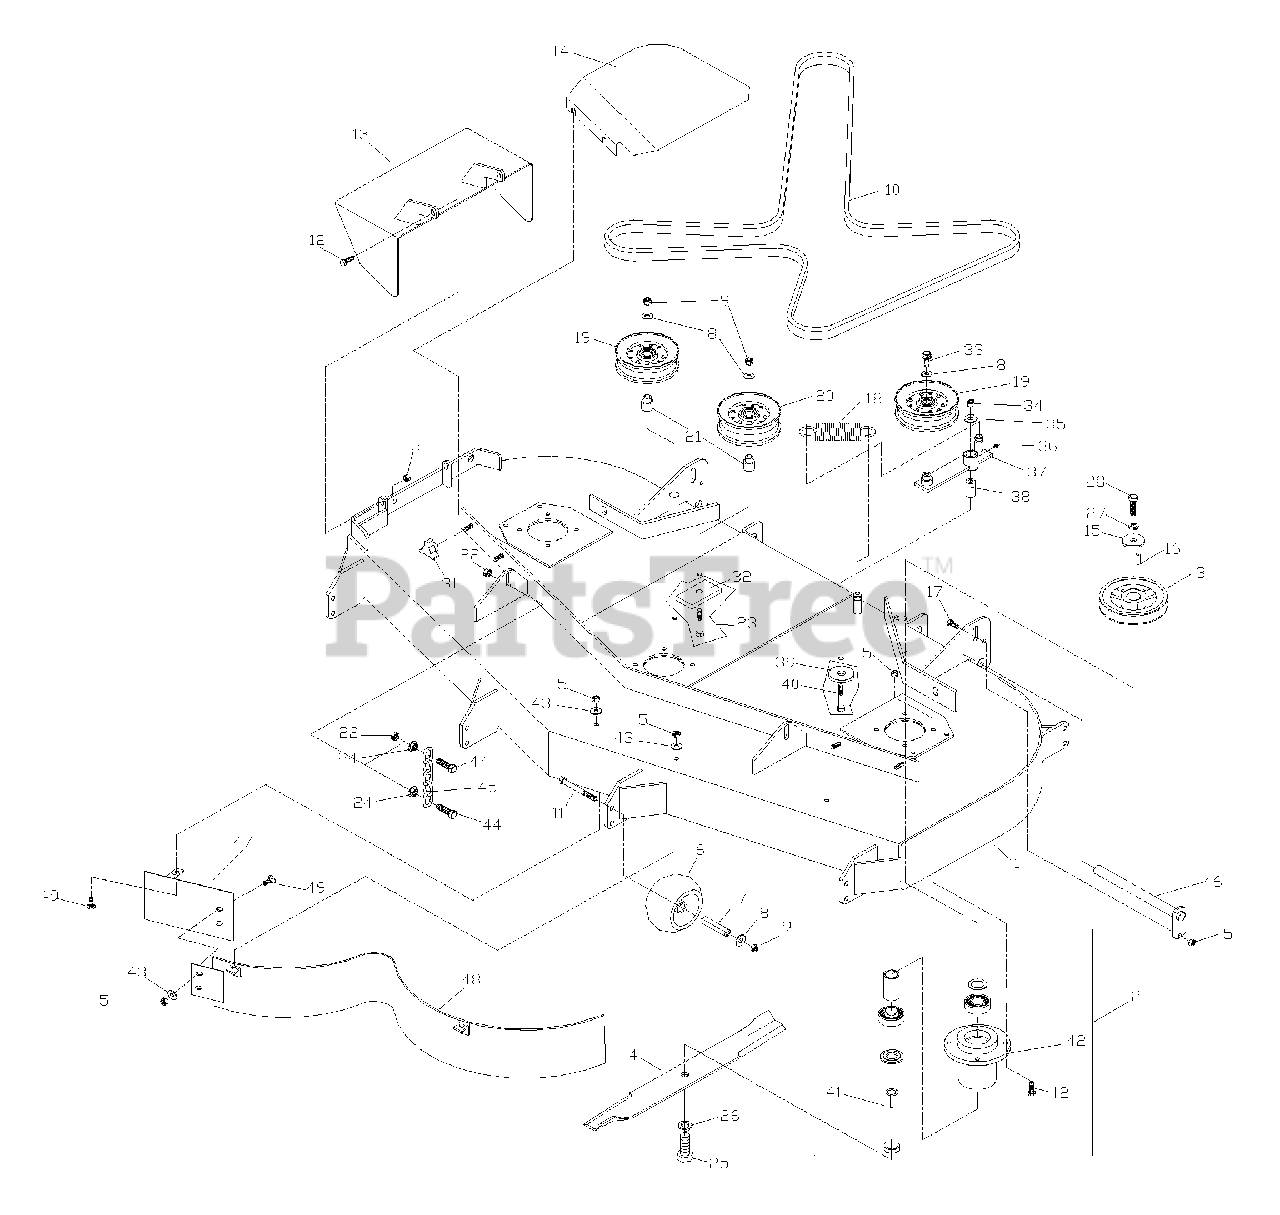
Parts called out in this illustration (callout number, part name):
1	DECK W/DECALS
2	CUTTER HOUSING ASM
2	BEARING KIT, CUTTER HOUSING
4	BLADE, 18"
5	NUT 5/16 LOCK
8	3/8 FLAT WASHER
9	NUT 3/8 LOCK
10	BELT
11	HCS 3/8 X 3.5
12	HCS 5/16 X 1.00
13	DISCHARGE CHUTE
14	BELT SHIELD RT
14	BELT SHIELD LT
16	KEY 1/4 SQ
17	HCS 5/16 X 750
19	PULLEY 1.31
20	PULLEY 1.62
21	IDLER BUSHING
22	NUT 7/16 LOCK
23	HCS 3/8 X 2.5
24	NUT 7/16 WHIZ
25	HCS 5/8F X 1.25
26	WASHER 5/8 LOCK
27	7/16 LOCK WASHER
28	HCS 7/16F X 1.5
32	PAD
33	HCS 3/8 X 1.0 SERR
34	NUT 1/2 NYLOC
35	WASHER 1/2 FLAT
36	ZERK
38	PIVOT BUSHING
39	SUPPORT WASHER
40	HCS 1/2 X 3.25
43	5/16 FLAT WASHER
44	HCS 7/16 X 1.5
45	LIFT CHAIN
47	BAFFLE, CENTER
48	BAFFLE, MAIN
49	RHSNB 5/16 X 5/8
